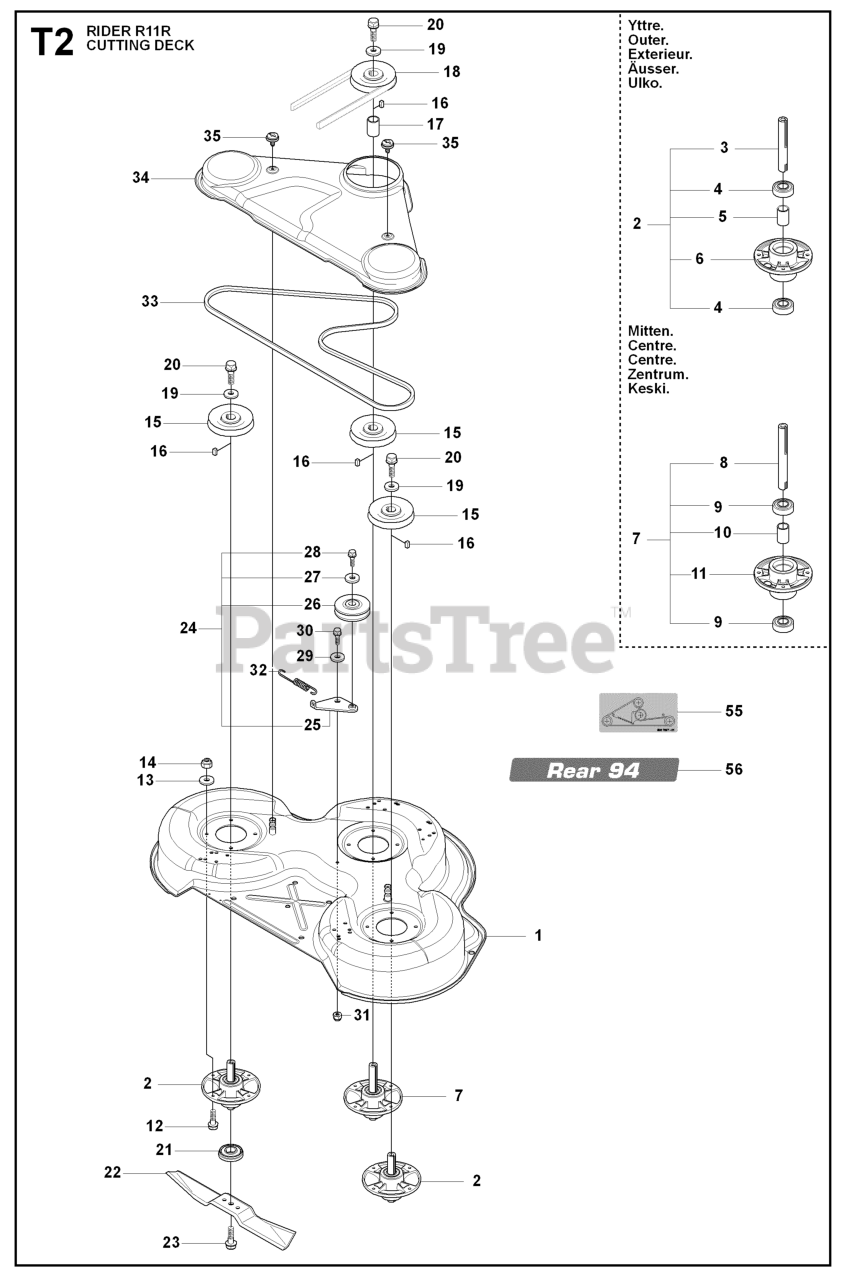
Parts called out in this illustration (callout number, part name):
2	RP SPINDLE ASSY
6	BEARING HOUSING
11	BEARING HOUSING
13	WASHER BRB 8.4X17
14	LOCKNUT M8
17	SPACING SLEEVE
21	BLADE BRACKET
26	PULLEY
29	WASHER
31	LOCKNUT M8
